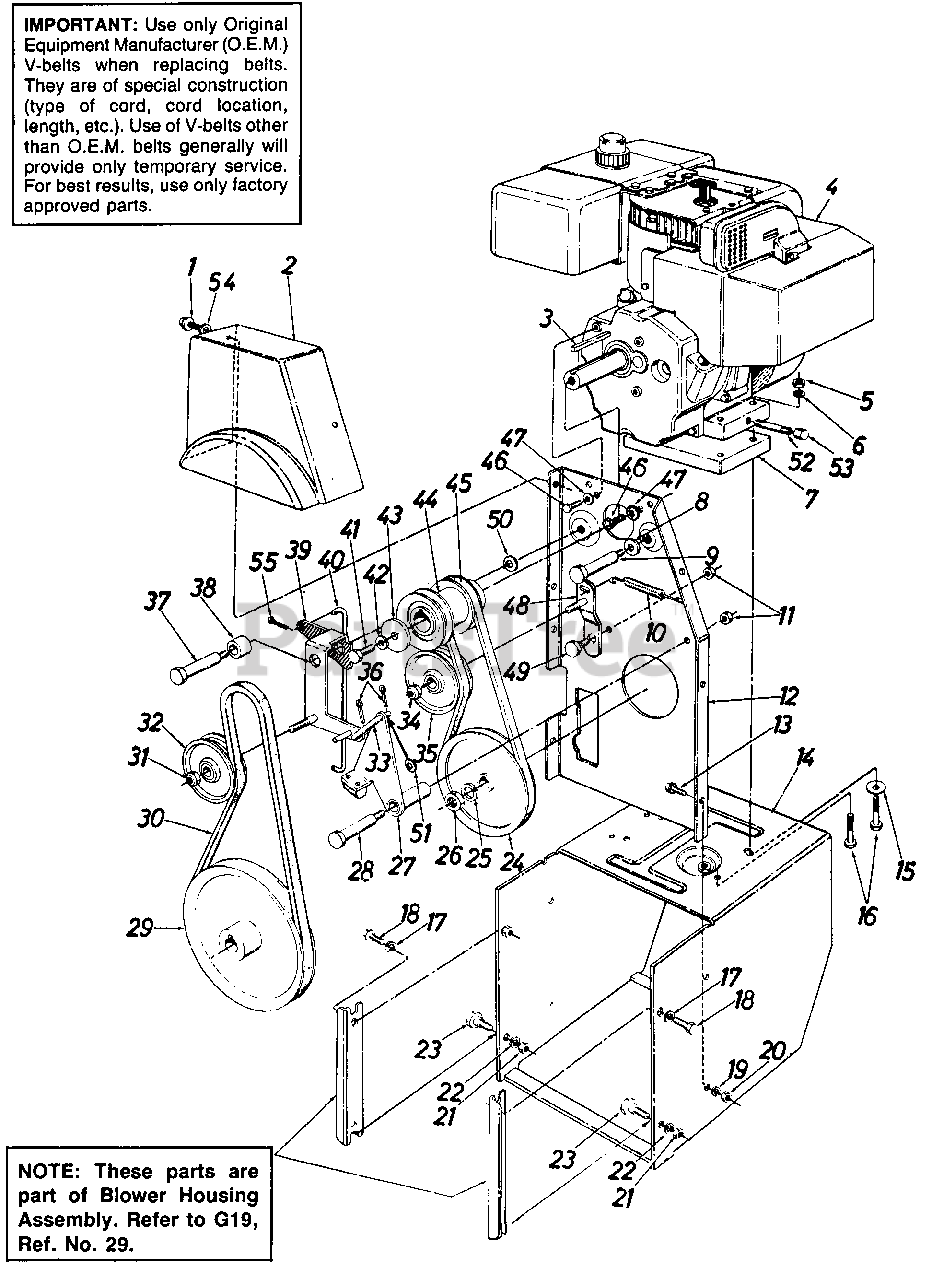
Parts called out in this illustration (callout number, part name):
1	SCREW-HEX HD TAP
2	COVER-BELT
3	KEY-SQ 1/4 X 1.50
5	NUT-HEX 5/16-18
6	WASHER-LOCK-5/16
7	BLOCK-ENGINE SPACER
8	WASHER-BELL .400 ID X .88 X .060
9	SCREW-SHLD .498 DIA X 3.00
10	SPRING-EXTENSION
11	NUT-HEX CENTER L-3/8-16
12	BRACKET ASSY-ENG
13	SCREW-HEX SEMS 5/16-18 X .75
14	FRAME ASSY
15	WASHER-FL-.344 X .62
16	SCREW-HEX
17	WASHER-HDL 3/8
18	SCREW-PILOT 3/8-16 X .88
19	WASHER-LOCK-5/16
20	NUT-HEX 5/16-18
21	NUT-HEX 3/8-16
22	WASHER-HDL 3/8
23	SCREW-SHLD .498 DIA X .340
25	WASHER-LOCK-5/8
26	NUT-HEX INS L-5/8-18
27	BRACKET ASSY-BRAKE
28	SCREW-SHLD .498 DIA X 2.005
29	PULLEY-V-1/2 ID X 10.0 OD
30	BELT-V 1/2 X 45
31	NUT-HEX INS L-3/8-24
32	PULLEY-IDLER-FLAT-3.00
33	LINK ASSY-BRAKE
34	NUT-HEX INS L-3/8-24
35	PULLEY-IDLER-FLAT-3.00
36	PIN-COTTER-3/32 DIA X .75
37	SCREW-SHLD .625 DIA X 2.75
41	SCREW 3/8-24X1.25 GR5
42	WASHER-HDL 3/8
43	WASHER-FL
44	PULLEY-ENGINE
45	BELT-3V-35.5
46	SCREW-HEX 5/16-24 X .62
47	WASHER-BELL .337 X .867 X .057
48	BRACKET ASSY-DR IDLER
49	SCREW-SHLD .625 DIA X .163
50	WASHER-BELL .3/8ID X 1.12OD X .030
51	WASHER-FL-.385 ID X .62 OD X .033
52	NIPPLE-PIPE
53	CAP-HEX PIPE THD
54	WASHER-FL-.344 X .62
55	PIN-INTERN COT-5/16 DIA
